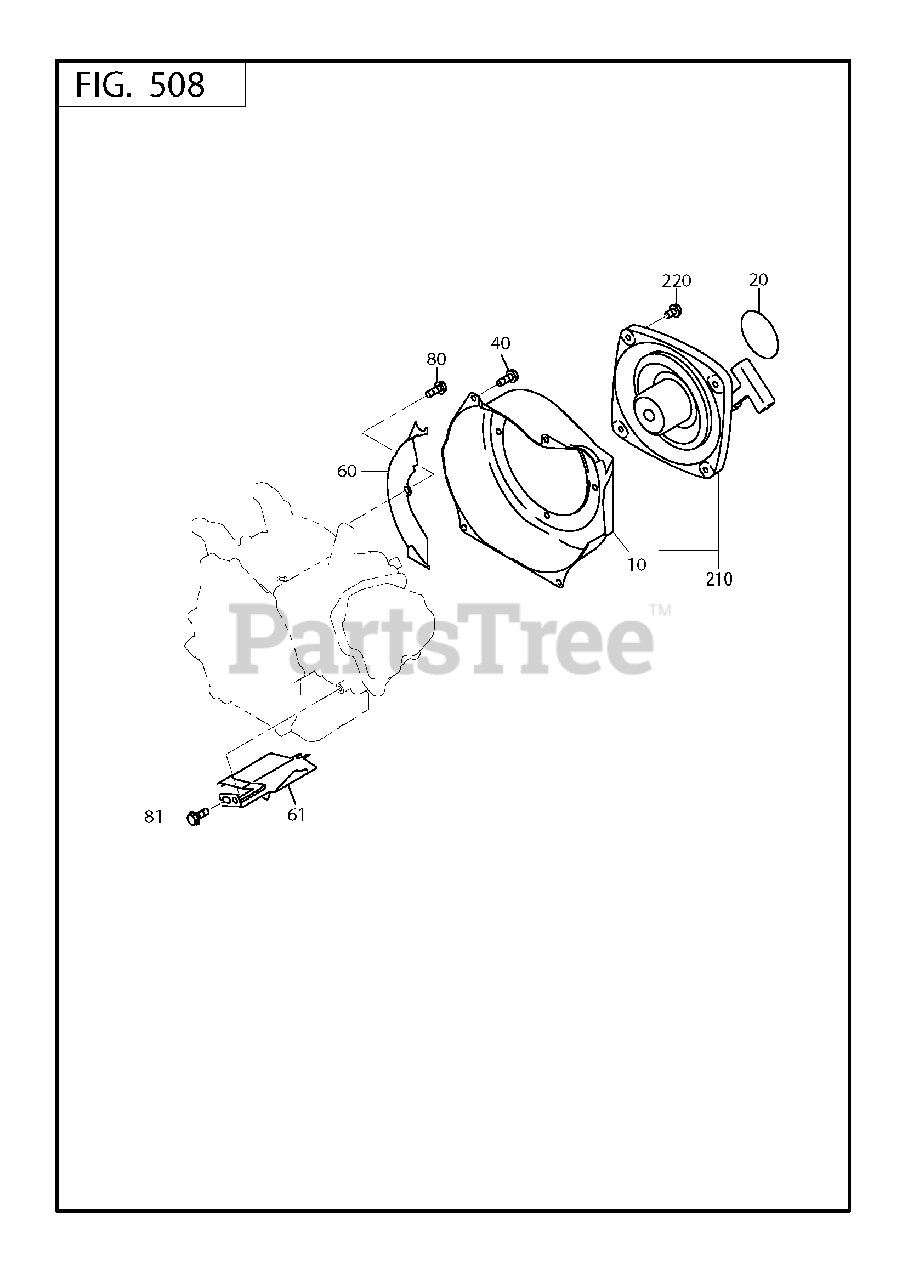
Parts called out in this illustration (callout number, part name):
10	BLOWER HOUSING CP
20	LABEL, TRADEMARK
60	BAFFLE 1 CP, CASE
61	BAFFLE 2, HEAD
210	RECOIL STARTER AY
220	BOLT AND WASHER AY
